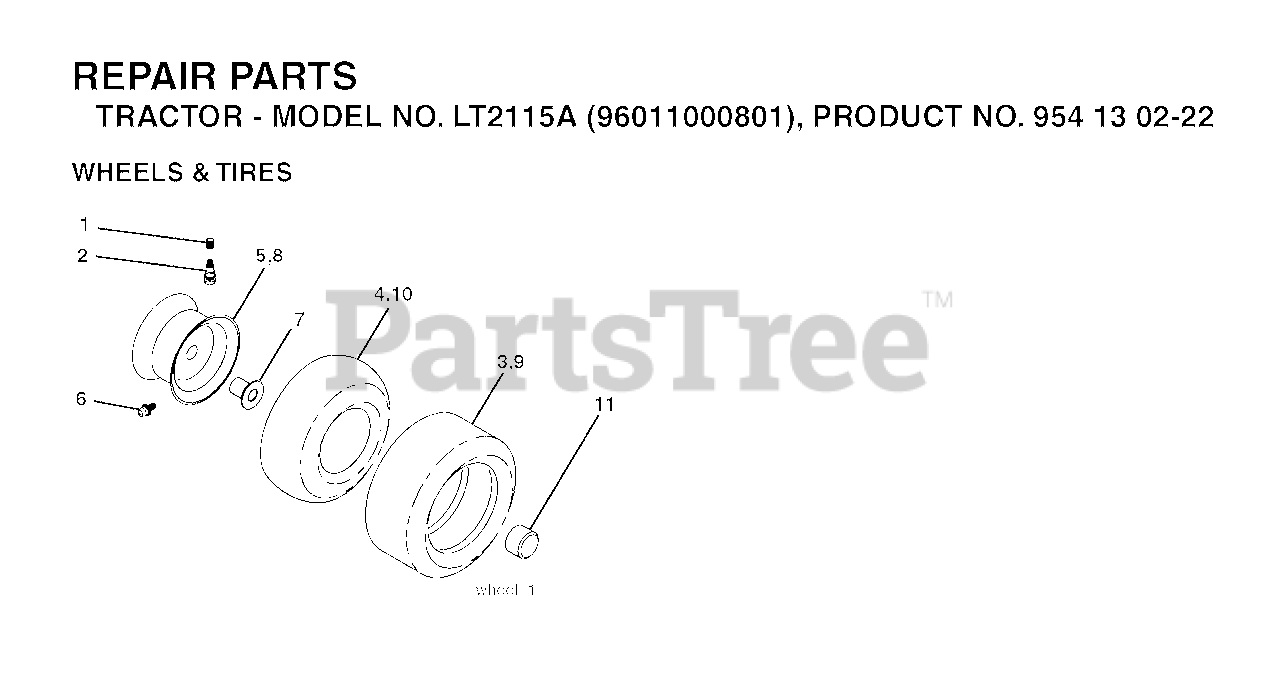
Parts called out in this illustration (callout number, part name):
1	VALVE CAP
2	VALVE STEM LT
3	TIRE HEAVY DUTY
4	TUBE.5.3/4.5/6
5	RIM ASM 6" FRONT SILVER
6	FITTING LT
7	BEARING T
8	RIM ASM 8" REAR SILVER
9	TIRE HEAVY DUTY
10	TUBE
11	CAP, AXLE BLK
